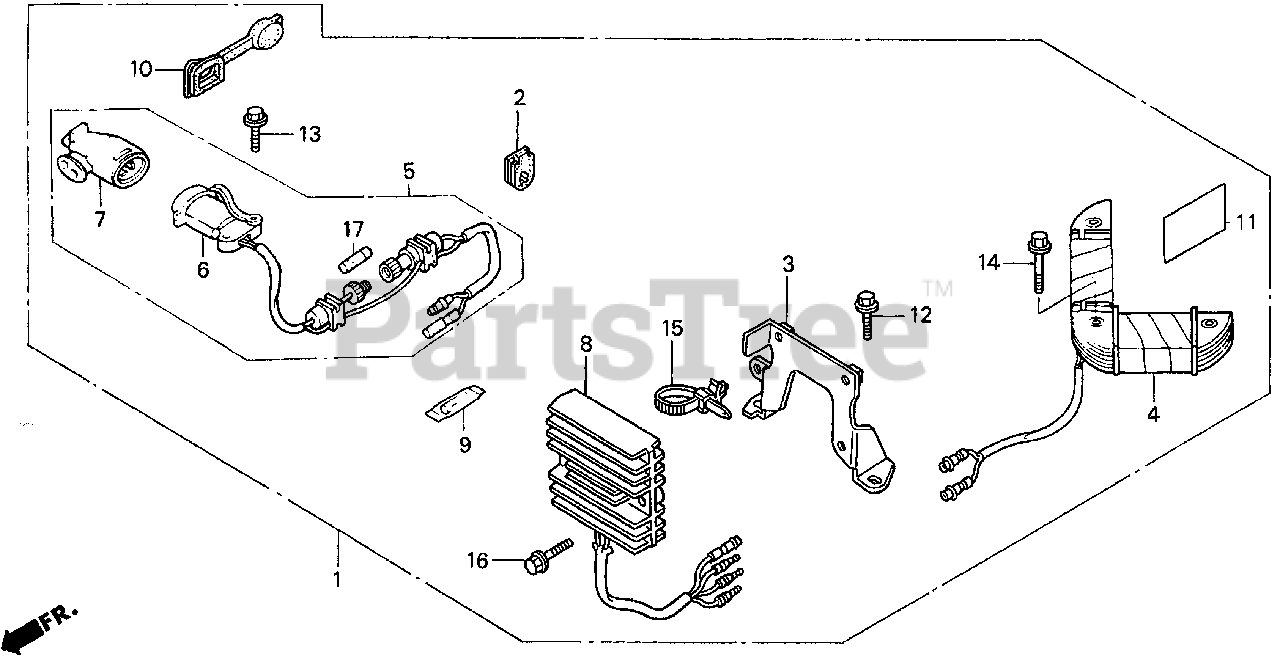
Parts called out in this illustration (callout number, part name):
1	RECEPTACLE KIT, CHARGE (10A-A) Use up to Frame SN 1001560.
1	RECEPTACLE KIT, CHARGE (10A) Use from Frame SN 1001561.
2	GROMMET, WIRE
3	BRACKET, REGULATOR
4	COIL ASSY., CHARGE (12V-10A)
5	RECEPTACLE ASSY., CHARGE
6	RECEPTACLE
7	PLUG, RECEPTACLE
8	REGULATOR ASSY. (RECTIFIER)
9	FUSE, SPARE (15A)
10	GROMMET, CASE (LOWER) (C)
11	MARK, RECEPTACLE (10A) Use up to Frame SN 1001560.
11	MARK, RECEPTACLE (10A) Use from Frame SN 1001561.
12	BOLT, FLANGE (6X12)
13	BOLT, FLANGE (5X22)
14	BOLT, FLANGE (6X35)
15	STRAP, CABLE (118MM) *NH1L*
16	BOLT, FLANGE (6X20)
17	FUSE A (15A)
